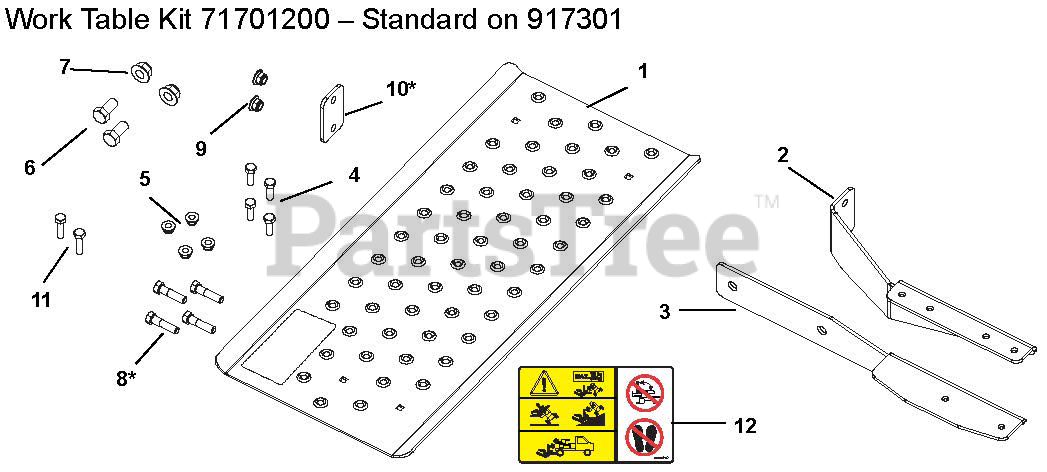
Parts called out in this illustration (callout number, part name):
1	Bracket, Work Table
2	Bracket, Rear Table Mount
3	Bracket, Front Table Mount
4	Bolt, Round Head Square Neck .312-18 x 1
5	Nut, Nyloc Flange .312-18
6	Bolt, Hex .50-13 x 1
7	Nut, Locking Top Flange .50-13
8	Bolt, Hex .38-16 x 1.5
9	Nut, Locking Top Flange .38-16
10	Spacer Plate, Work Table
11	Bolt, Hex .38-16 x 1.25
12	Decal, Splitter Table
